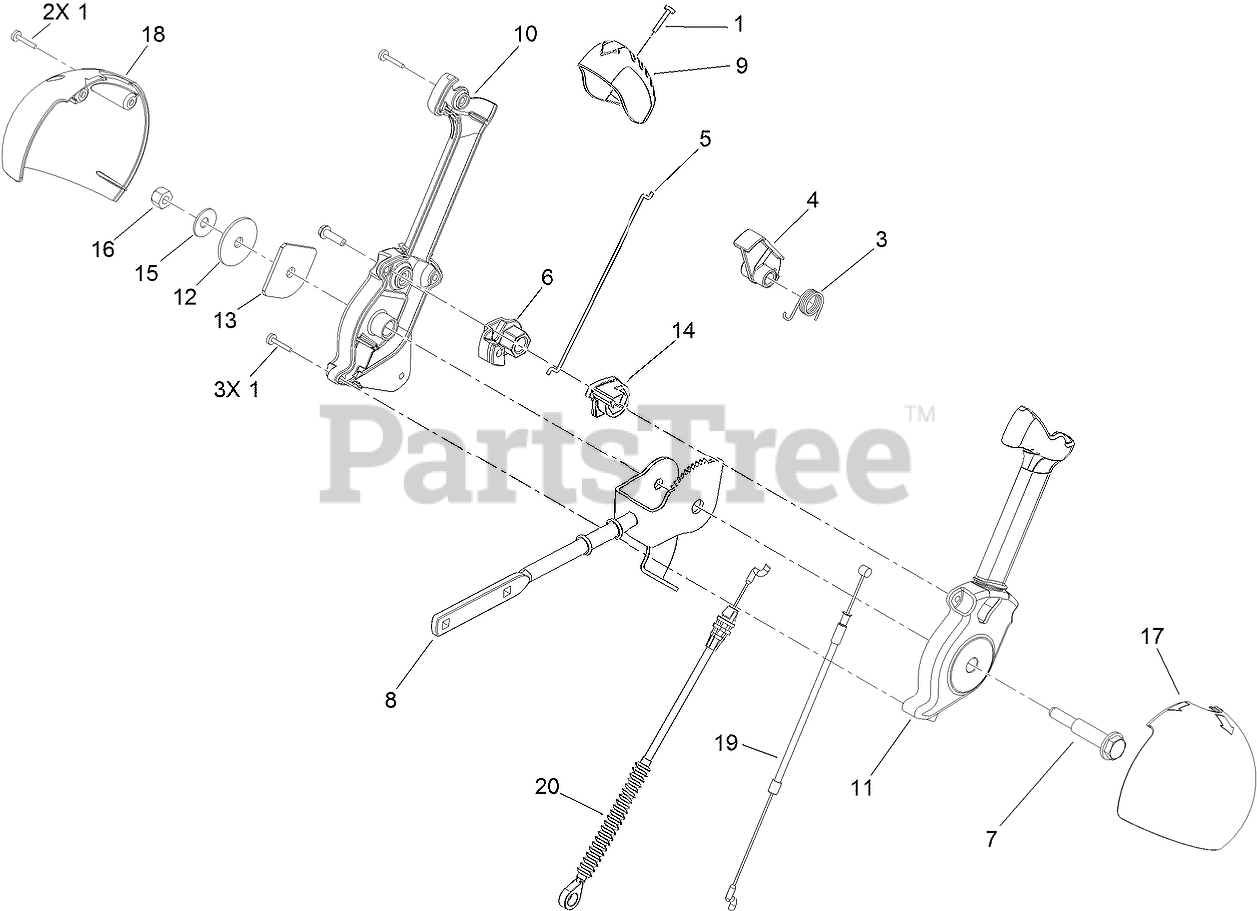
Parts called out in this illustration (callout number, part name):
1	SCREW-PPH
3	SPRING-TORSION
4	TRIGGER-LATCH
5	LINK-LATCH
6	LEVER-CABLE, DEFLECTOR
7	SCREW-SHOULDER
8	ROD-CONTROL, CHUTE
9	CAP-LEVER
10	LEVER-CONTROL, CHUTE (RH)
11	LEVER-CONTROL, CHUTE (LH)
12	WASHER-NYLON
13	PLATE-FRICTION
14	PAWL-LATCH
15	WASHER-BELLEVILLE
16	NUT-LOCK, NI
17	COVER-LEVER, CHUTE (LH)
18	COVER-LEVER, CHUTE (RH)
19	CABLE-RELEASE, CHUTE
20	CABLE-CONTROL, DEFLECTOR
